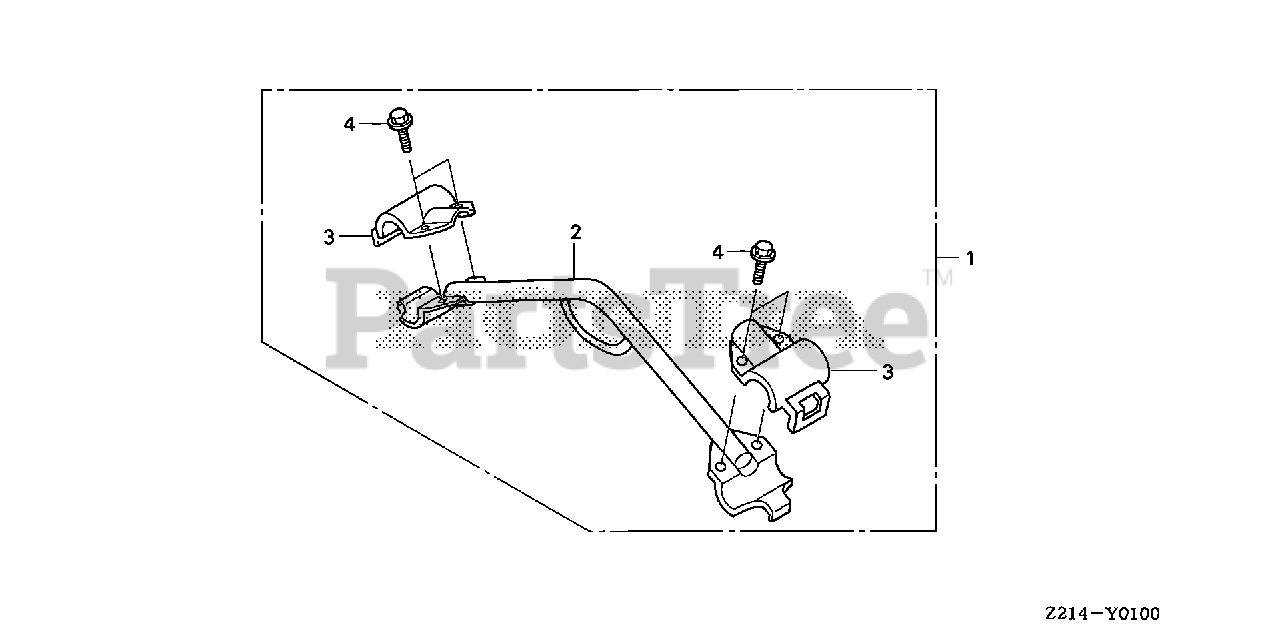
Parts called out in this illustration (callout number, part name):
1	HANGER KIT *NH105* (MAT BLACK)
2	HANGER *NH105* (MAT BLACK)
3	BRACKET, HANGER (UPPER) *NH105* (MAT BLACK)
4	BOLT, FLANGE (8X16)
